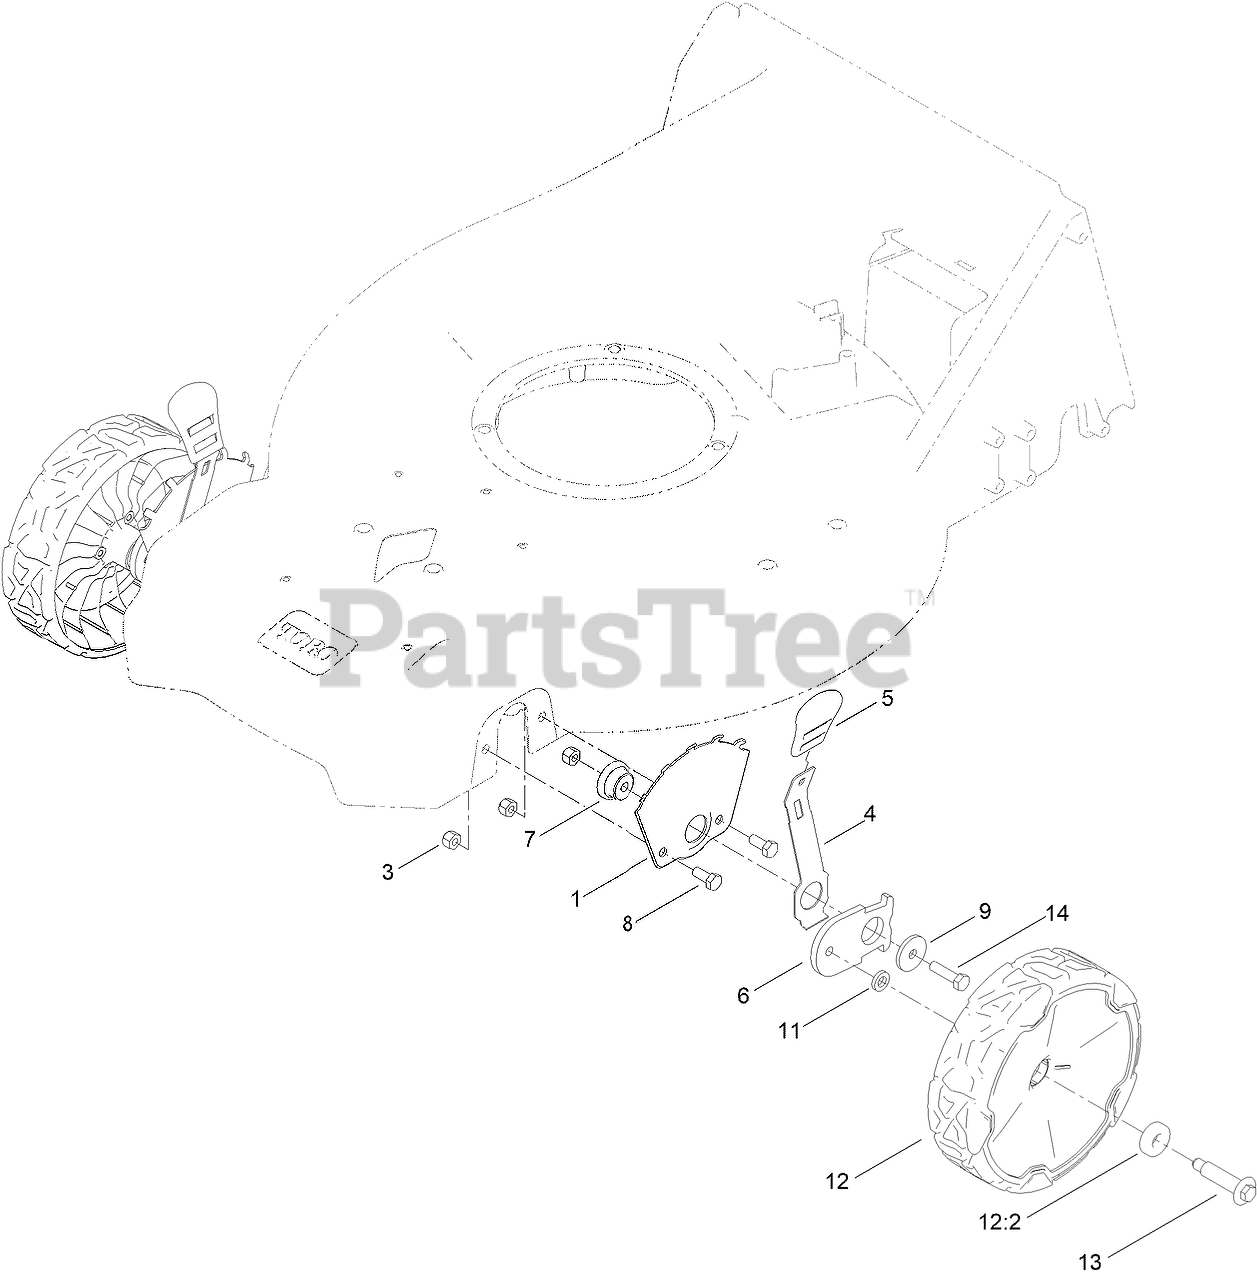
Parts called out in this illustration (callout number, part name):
1	PLATE-HOC,FRONT FSVQ WEDNESDAY
3	NUT-LOCK, NI
4	ARM-SPRING
5	KNOB-HOC
6	ARM-PIVOT, FRONT
7	BUSHING-MOUNT, HOC
8	SCREW-HH
9	WASHER-FLAT
11	WASHER-WHEEL BOLT
12	ASM-WHEEL, 8" (BEARINGS)
12:2	BEARING-WHEEL
13	WHEEL BOLT
14	SCREW-HH
